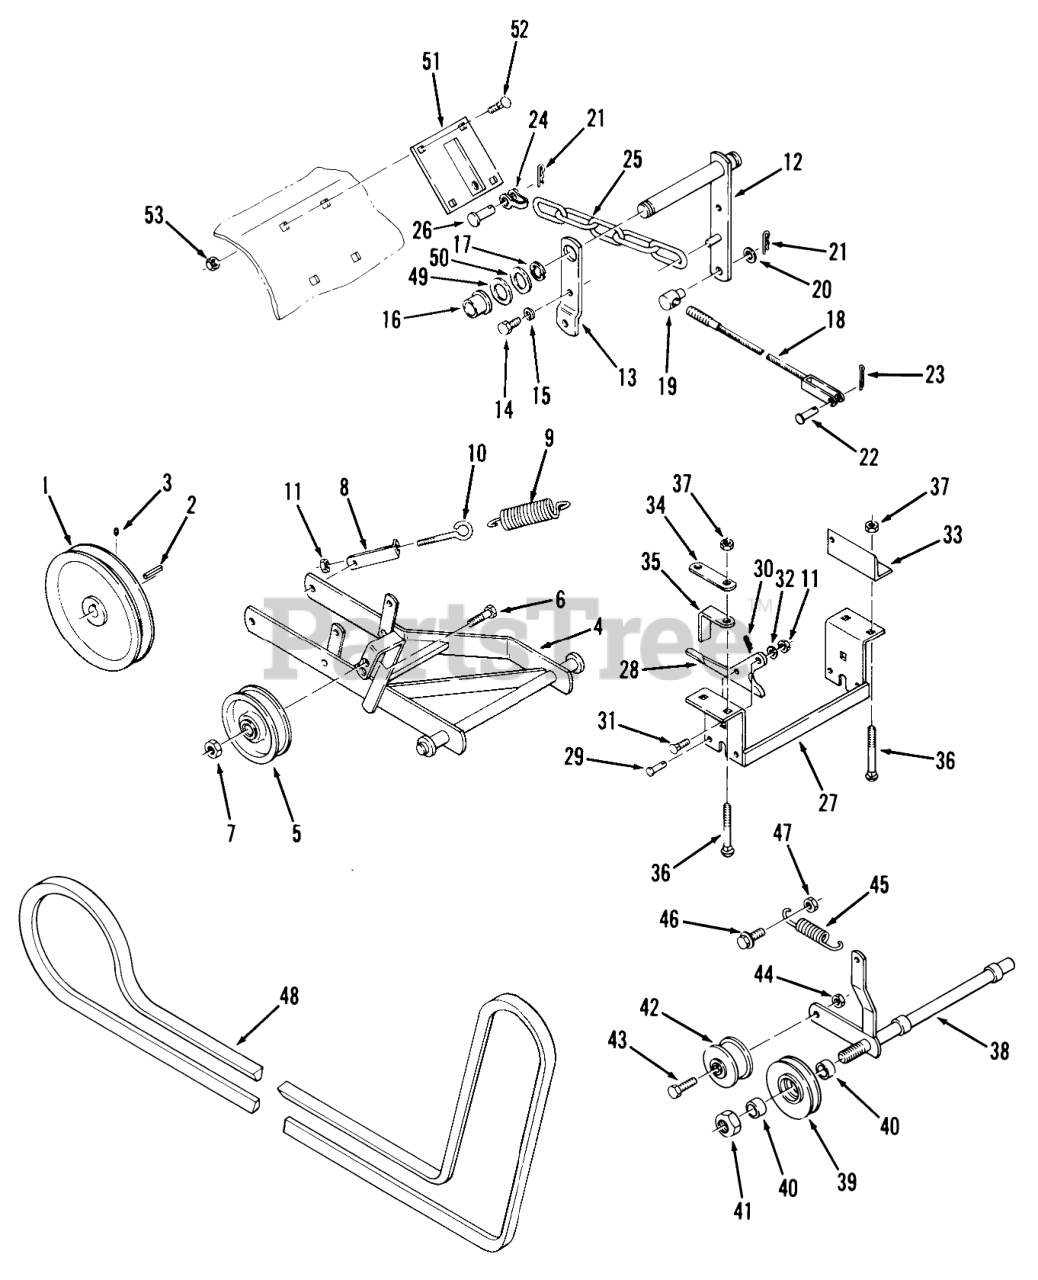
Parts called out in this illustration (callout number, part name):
1	Pulley
2	KEY-STRAIGHT
3	Setscrew-Square Head
4	Hitch
5	Flat Idler
6	HEX HD CAP SCREW
7	Nut
8	Bracket-Spring
9	SPRING
10	EYEBOLT
11	NUT
12	Lever Assy.
13	LOCK BRACKET R
14	Bolt
15	Lockwasher
16	BUSHING
17	E-RING
18	ASSY-LIFT CABLE
19	TRUNNION-CLUTCH ROD
20	Washer
21	Hairpin
22	Pin
23	Cotter Pin
24	Clevis
25	CHAIN-LIFT
26	Clevis Pin
27	Bracket
28	PLATE-LATCHING
29	Pin
30	Hairpin
31	Bolt
32	Washer
33	Link
34	BRACKET-REAR LINK MOUNTING
35	SPACER-BRACKET
36	Bolt-Carriage
37	Nut
38	Front Idler
39	Pulley-V
40	Spacer
41	Nut
42	IDLER PULLEY
43	BOLT
44	Nut
45	SPRING-BRAKE
46	HHCS
46	BOLT
47	Nut
48	V BELT
49	WASHER
50	WASHER-SHIM
51	Lift Plate
52	Bolt
53	Nut
